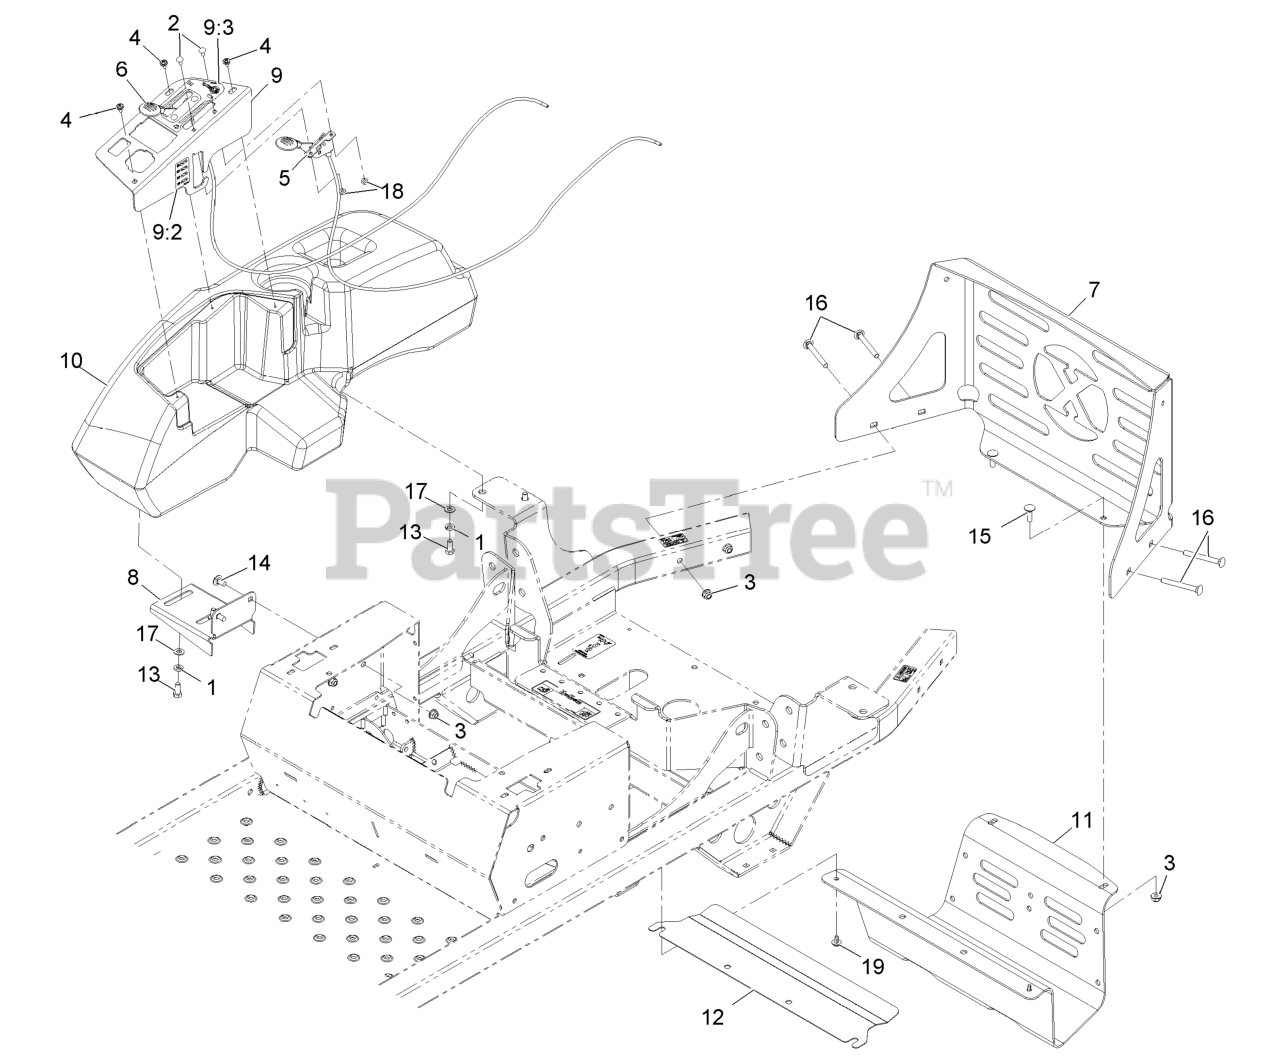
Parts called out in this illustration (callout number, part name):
1	WASHER-LOCK
2	BOLT-CARR
3	NUT-HF, NI
4	SCREW-PPH
5	CONTROL,THROTTLE
6	CONTROL,CHOKE
7	PANEL,REAR GUARD
8	BRACKET-TANK AND FENDER
9	ASM,CONTROL PANEL W/DECAL
9:2	DECAL,FUSE BLOCK
9:3	DECAL-THROTTLE CHOKE
10	CONSOLE,RH
11	GUARD-MUFFLER
13	SCREW-HH
14	SCREW-CARR
15	BOLT-CARR
16	SCREW-CARR
17	WASHER-PLAIN
18	NUT-LOCK, NI
19	SCREW-HHFTF
